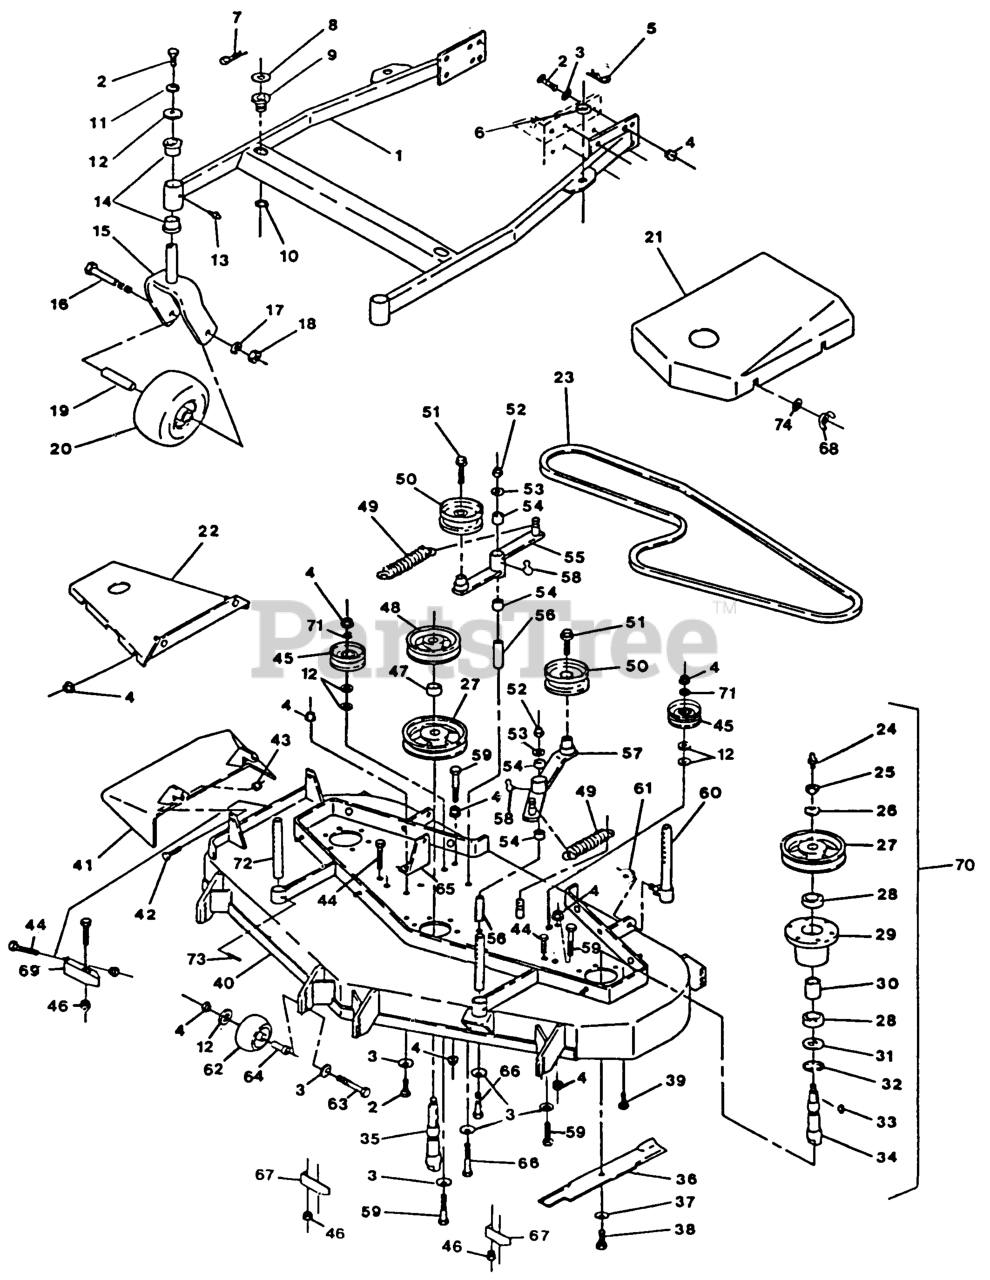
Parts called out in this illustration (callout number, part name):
5	PIN,HAIR COTTER
8	WASHER-FLAT
9	BUSHING-DECK
14	BEARING-FLANGED
23	BELT,BLADE DRIVE
26	WASHER-SPRING
27	SHEAVE,BLADE DRIVE
30	SPACER,BEARING
31	SEAL,MECHANICAL DUST
32	RING,SNAP WLDS N5000-244
34	SPINDLE-OUTER BLADE
35	SPINDLE-CENTER BLADE
37	WASHER-SPRING
39	SCRW,TPTTE HH
41	WLD,CHUTE DISCHARGE
45	IDLER,PULLEY
47	SPACER-TUBE
48	SHEAVE,MOWER DRIVE
49	SPRING-EXTENSION
50	IDLER,PULLEY
54	SLEEVE-BEARING
55	ASM,IDLER ARM
56	BUSHING-PIVOT, IDLER
57	ASM,IDLER ARM
62	ROLLER-SCALP, ANTI
64	BUSHING-ROLLER
65	BRACKET,SPRING ANCHOR
66	SCREW-HH
68	NUT-WING
69	WLD,BAFFLE DISCHARGE
72	ROD,DECK SUPPORT
